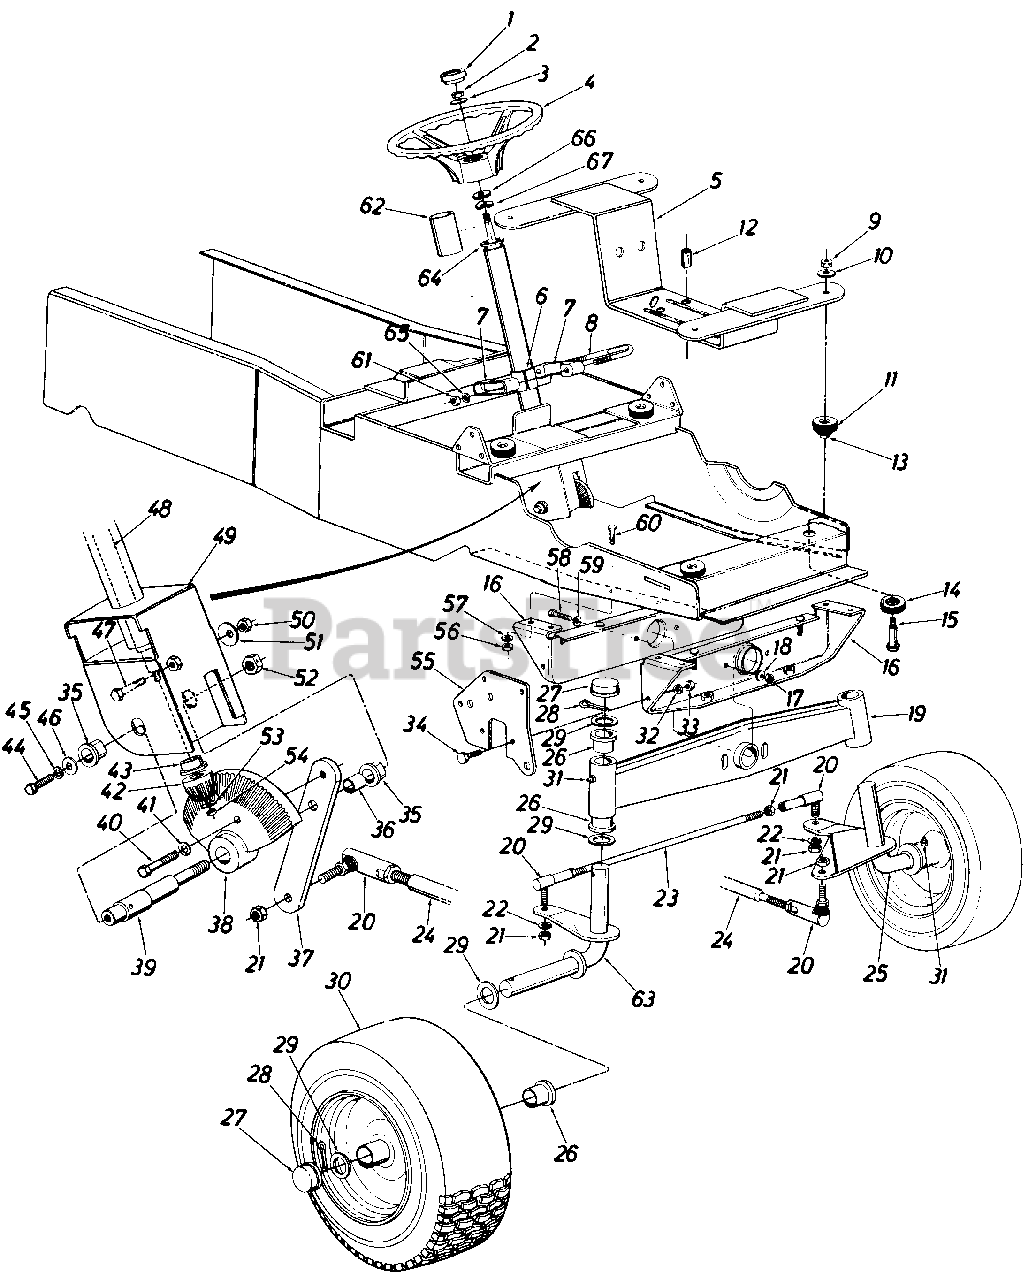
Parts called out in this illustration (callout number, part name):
1	Steering Wheel Cap
2	Hex Cent. L-Nut 5/16-18 Thd.
3	Belleville Wash.
4	Steering Wheel
5	Eng ine Support Ass'y.
6	Tube Spacer
7	Bearing Block
8	"U"-Clamp
9	Hex Cent. L-Nut 5/16-18 Thd. *
10	Bell-Wash.
11	Engine Mount
12	Engine Mount Spacer
13	Engine Mount
14	Engine Mount
15	Shoulder Scr.
18	Belleville Wash.
19	Pivot Bar Ass'y.
20	Tie Rod End
21	Hex Nut 1/2-20 Thd.
22	L-Wash. 1/2" Scr.
23	Tie Rod
24	Drag Link
25	Front Axle Ass'y.-L.H.
26	Plastic Flange Bearing 1.0" I.D.
27	Dust Cover
28	Cotter Pin 3/16" Dia. x 1.50" Lg.*
29	Fl-Wash. 1.0" I.D.
30	Front Wheel Ass'y. Comp. 16 x 6.50
32	L-Wash. 3/8" Scr.
33	Hex Nut 3/8-16 Thd.*
34	Hex Scr. 3/8-16 x 1.00" Lg. *
35	Flange Bearing
36	Steering Gear Shaft Spacer
37	Steering Arm
38	Bevel Gear
39	Steering Gear Shaft
40	Hex Scr. 3/8-16 x 1.50" Lg.
41	L-Wash. 3/8" Scr.
42	Pinion Gear
43	Flange Bearing
44	Hex Scr. 3/8-16 x .75" Lg.
45	L-Wash. 3/8" Scr.*
46	Fl-Wash. 3/8" I.D. x 1.25 O.D.
47	Nylon Hex Screw
48	Steering Shaft
49	Steering Bracket Support Ass'y.
50	Hex Jam Nut 3/8-18 Thd.
51	Belleville Wash.
52	Hex Ins. L-Nut 1/2-20 Thd.
53	Fl-Wash. .344 I.D. x .62 O.D.
54	Hex Cent. L-Nut 5/16-24 Thd.
55	Front Pivot Brkt. Reinforcement
56	Hex Nut 3/8-16 Thd.
57	L-Wash. 3/8 " Scr.
58	Hex Scr. 3/8-16 x 2.50" Lg.
59	Belleville Wash.
60	Hex Scr. 3/8-16 x 1.00" Lg.
61	Hex Nut 5/16-18 Thd.
62	Steeri ng Tube Outer
63	Front Axle Ass'y.-R.H.
64	Ball Bearing
65	L-Wash. 5/16" Scr.*
66	Double "D" Flat Wash.
67	Wave Wash. .660 I.D. x .88 O.D.
